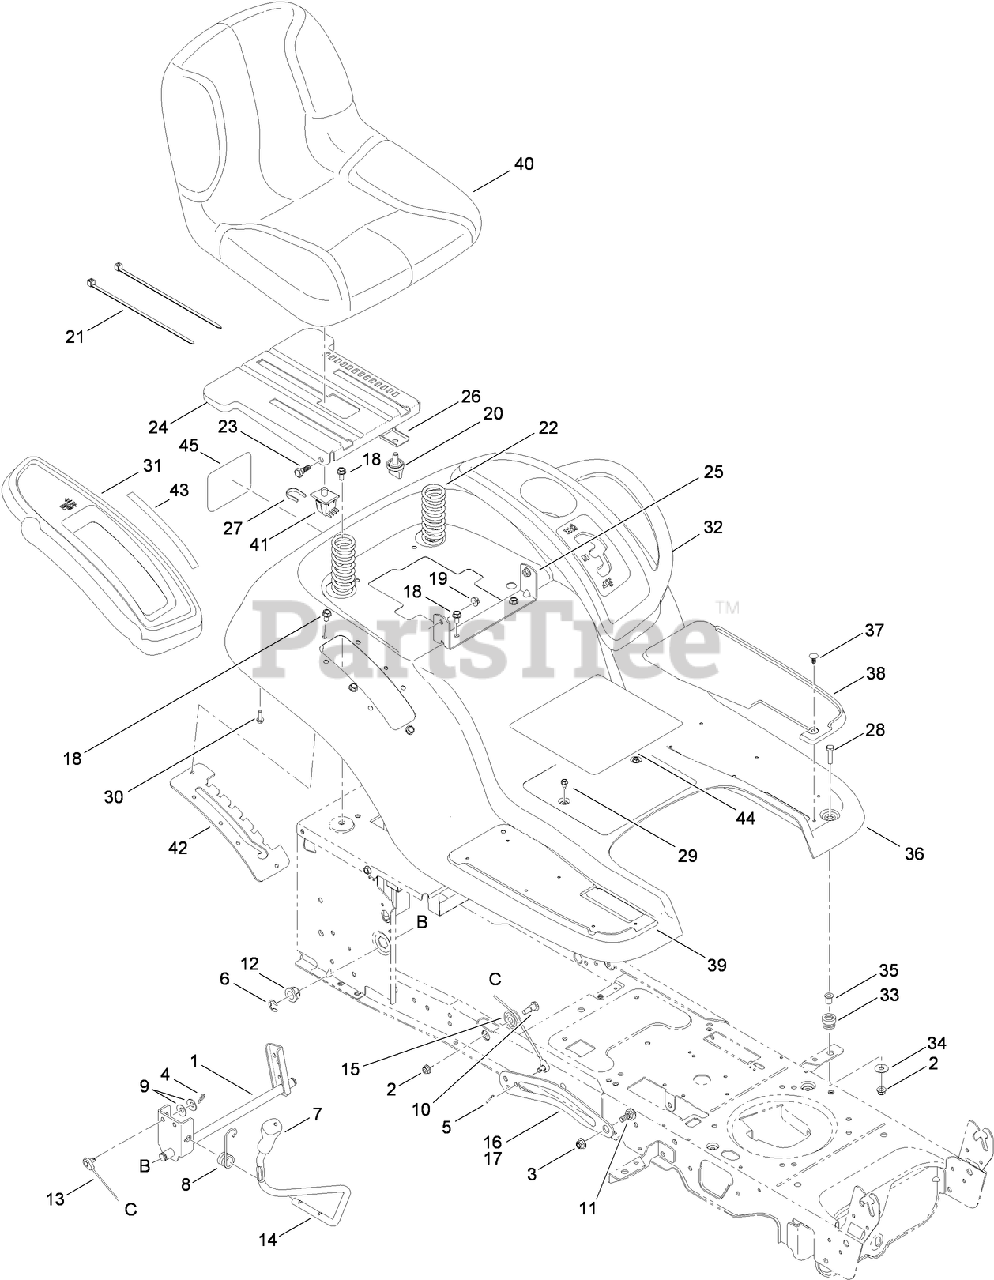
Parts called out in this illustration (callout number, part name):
1	LIFT SHAFT ASM
2	NUT-LOCK, FLANGE
3	NUT-LOCK, FLANGE
4	PIN-COTTER
5	PIN-COTTER
6	RING-E
7	GRIP-HANDLE
8	SPRING-TORSION
9	WASHER-SPRING
10	BOLT-SHOULDER
11	BOLT-SHOULDER
12	BEARING-FLANGE
13	CABLE-LIFT
14	HANDLE-LIFT
15	PULLEY-CABLE
16	ARM-LIFT, RH
17	ARM-LIFT, LH
18	SCREW-TAP
19	NUT-LOCK, FLANGE
21	TIE-CABLE
22	SPRING-COMPRESSION
23	BOLT-SHOULDER
24	BRACKET-MOUNT, SEAT
25	BRACKET-PIVOT, SEAT
26	BRACKET-KNOB, ADJUSTMENT
27	CLIP-RETENSION
28	SCREW-HH
29	SCREW-HWHTF
30	SCREW-TAP
31	COVER-FENDER, RH
32	COVER-FENDER, LH (W/CUPHOLDER)
33	GROMMET
34	WASHER-FLAT
35	SPACER
36	FENDER
37	CLIP-RATCHET
38	PAD-FOOT, LH
39	PAD-FOOT, RH
40	SEAT-HIGH
41	SWITCH-SEAT
42	BRACKET-LIFT
43	DECAL-HOC AND PTO
44	DECAL-SAFETY
45	DECAL-TORO
